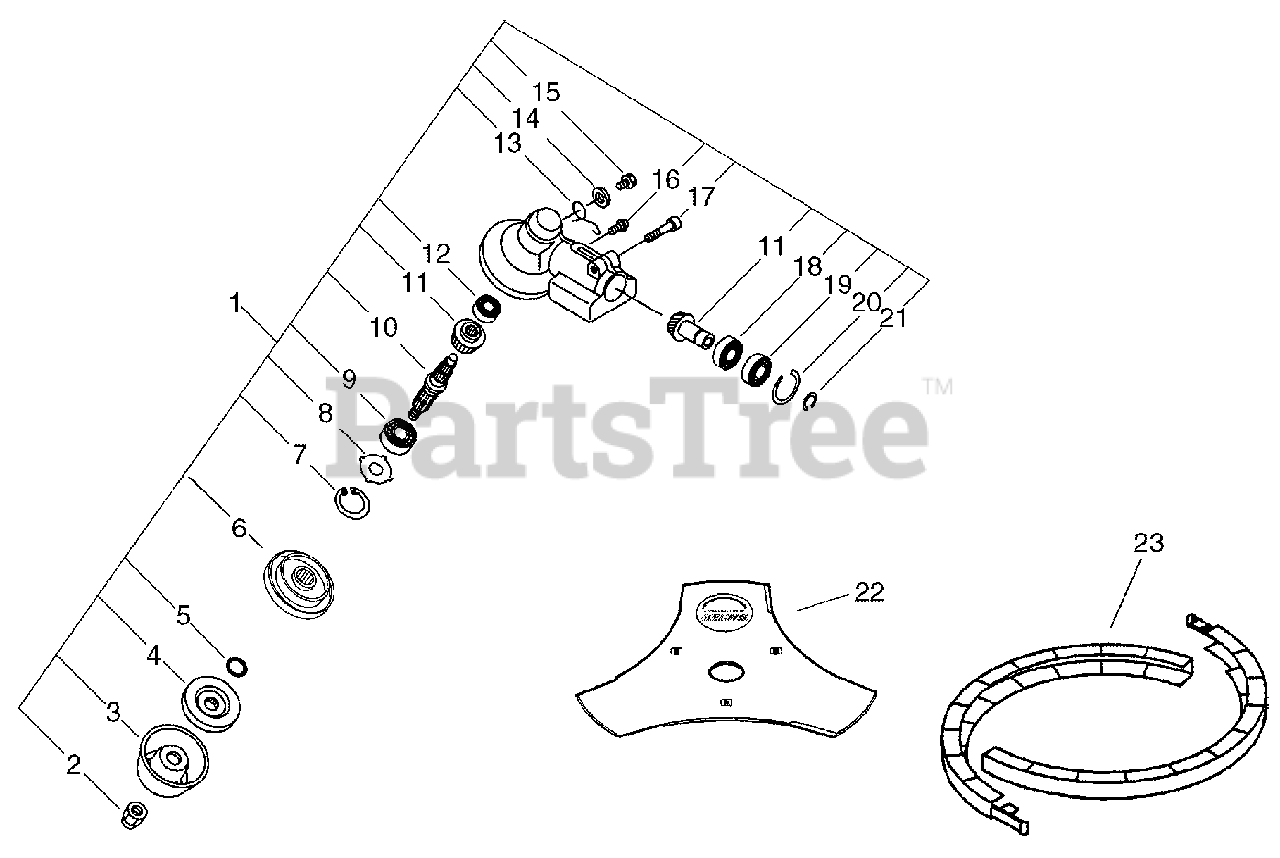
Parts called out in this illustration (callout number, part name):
1	CASE, GEAR
2	NUT, LOCK 10 - NYLON INSERT
4	PLATE, ADAPTOR - LOWER
5	O-RING 12 MM
6	RETAINER, BLADE
7	RING, SNAP Ø32
9	BEARING, BALL 6201
10	GEAR, SHAFT
11	GEAR SET
12	BEARING, BALL 626
13	SPRING, TORSION
14	WASHER 8.5×18×0.8T
15	BOLT M8×8
16	SCREW 5×10
18	BEARING, BALL 6900
19	BEARING, BALL 6900Z
20	RING, SNAP Ø22
21	RING, SNAP Ø10
22	BLADE, 9" 3-TOOTH
23	SCABBARD
